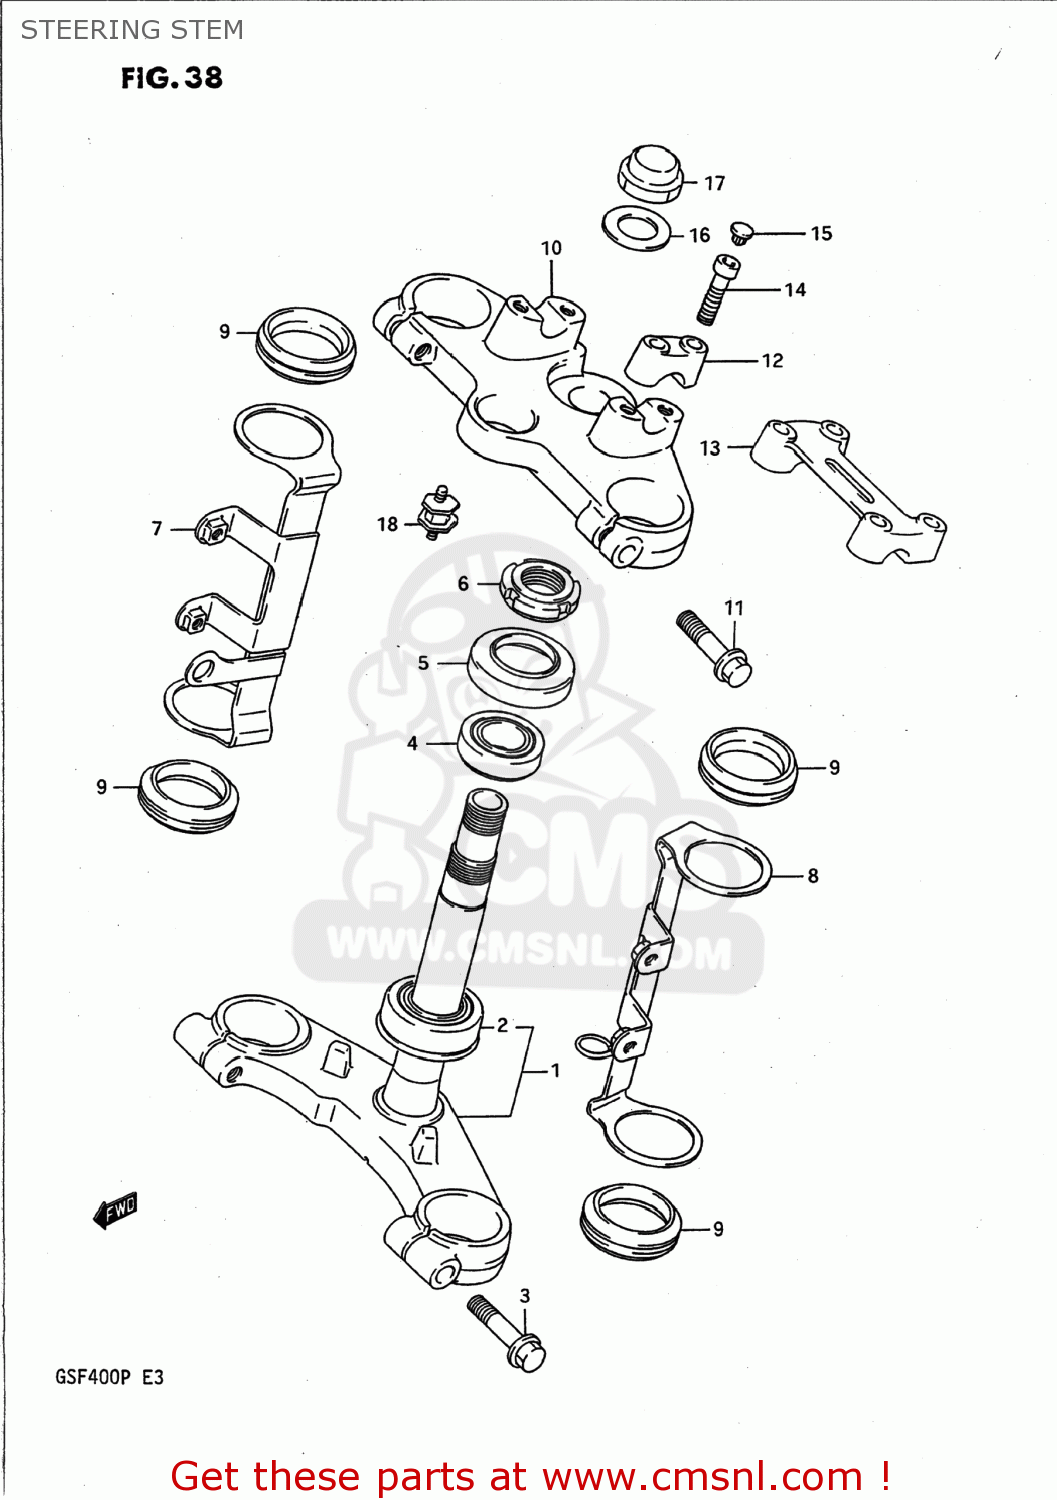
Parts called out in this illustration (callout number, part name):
1	STEM,STEERING
2	BEARING(30X55X17)
3	BOLT 10X45
4	TAPER,ROLLER BEARING
5	DUST SEAL,STEERING UPR
6	NUT,STEERING STEM(25X44X10)
7	BRACKET,HEADLAMP HOUSING,R
8	BRACKET,HEADLAMP HOUSING,L
9	DAMPER,HEADLAMP HSG BRACKET
10	HEAD,STEERING STEM
11	BOLT 10X45
12	HOLDER,HANDLE UPR
13	HOLDER,HANDLE
14	BOLT, LH
15	CAP(OD:11)
16	WASHER,UPPER
17	NUT,CAP
18	BOLT,SPEEDOMETER CUSHION
